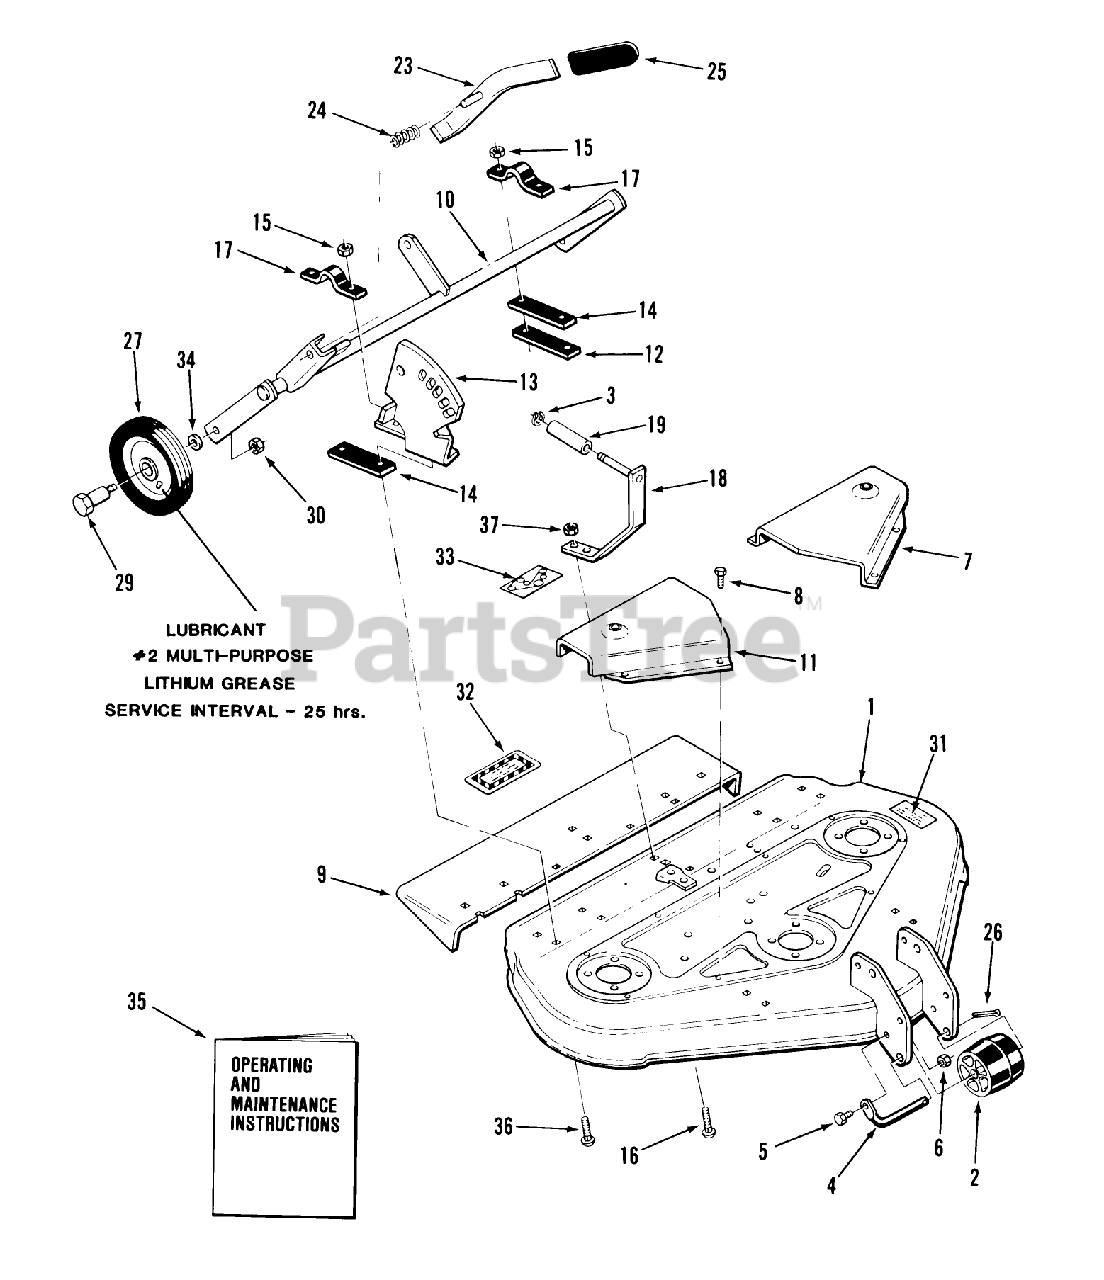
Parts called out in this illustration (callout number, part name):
4	ROLLER-SHAFT
10	ASSY GAGE WHEEL S *R
14	STRAP 1/16 *B
17	CLAMP
24	SPRING-COMPRESSION
27	WHEEL
29	BOLT-SHOULDER
33	DECAL-HEIGHT BELT
34	WASHER
35	Operating Maintenance Instructions
